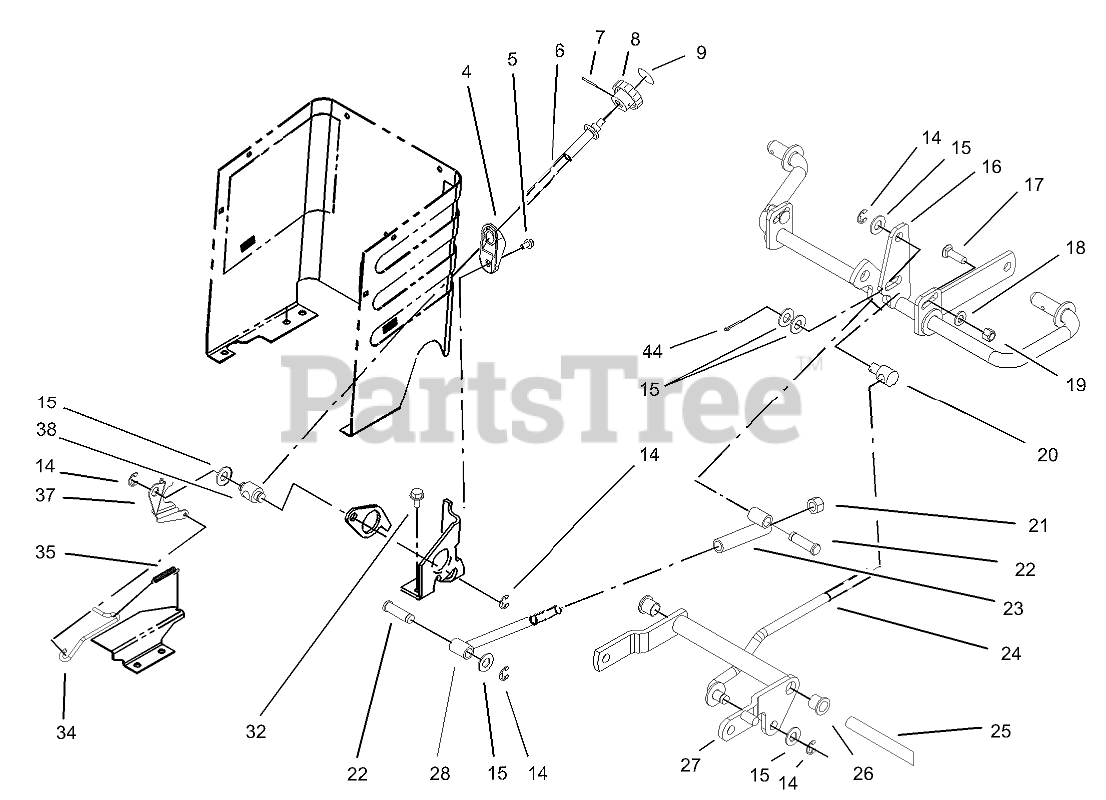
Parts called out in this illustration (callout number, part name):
4	WEDGE - HOC
5	SCREW-HWH
6	ROD - HOC
7	PIN-SPIROL
9	DECAL-HEIGHT KNOB
14	RING-RETAINING, EXTERNAL
15	WASHER-FLAT
16	SHAFT-GAGE
17	BOLT-CARR
18	WASHER-FLAT
19	NUT-LOCK, NI
20	ROD-TRUNNION LIFT
21	NUT-LOCK, NI
25	SHAFT-PIVOT, PEDAL
26	BUSHING-FLANGE
27	ARM-PIVOT
32	SCREW-HWHTF
34	ROD - HOC INDICATOR
35	SPRING - EXTENSION
37	PLATE - HOC GAGE
38	TRUNNION
44	PIN-COTTER
